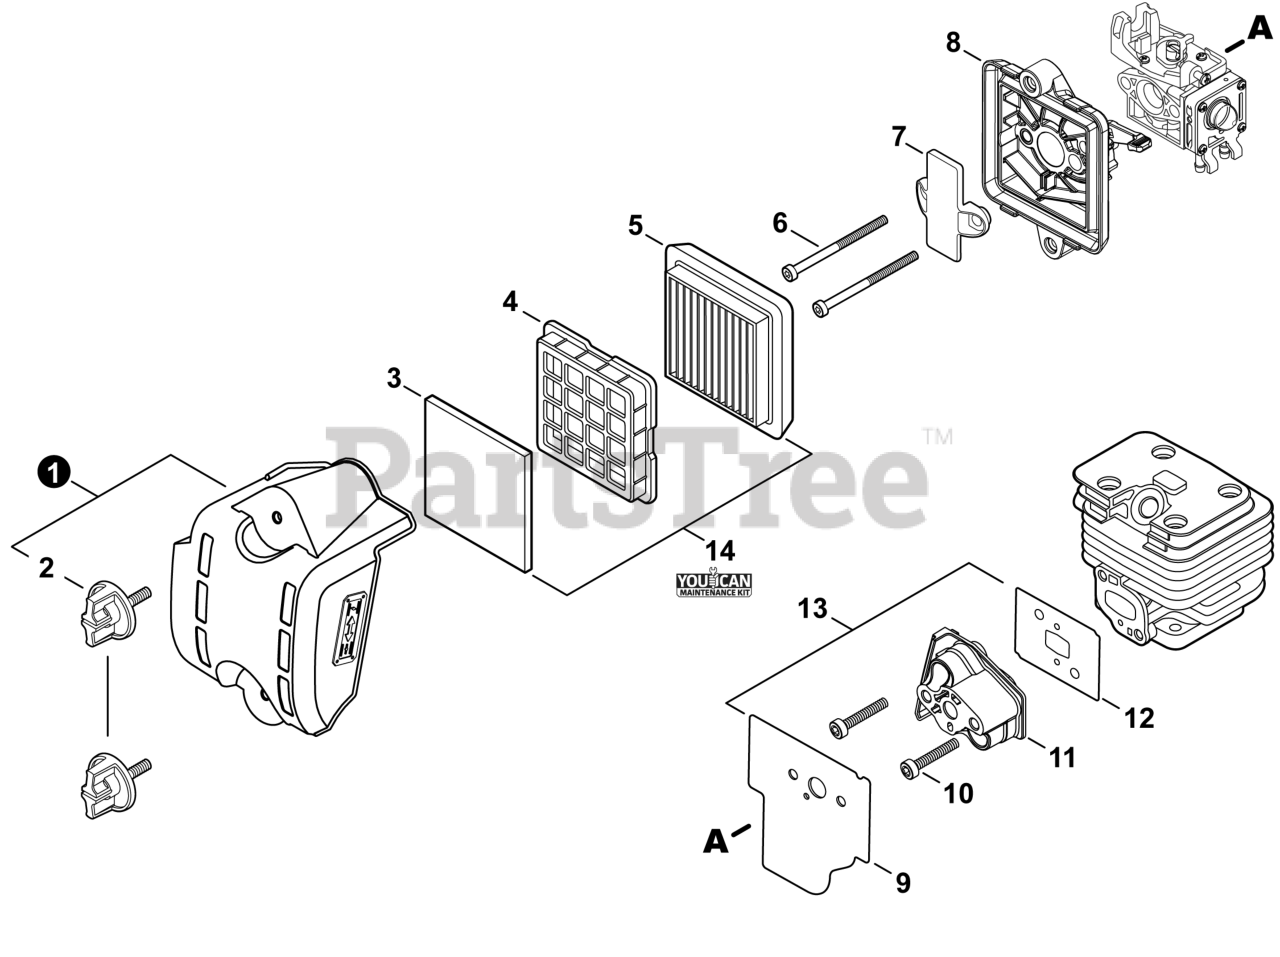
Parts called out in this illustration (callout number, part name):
1	COVER SET, AIR FILTER
2	KNOB, FASTENER
3	PRE-FILTER, FOAM
4	RETAINER, PRE-FILTER
5	FILTER, AIR
6	BOLT, TORX 5x60
7	PLATE, PREVENT
8	CASE, AIR FILTER
9	GASKET, INTAKE
10	BOLT 5x20
11	INSULATOR, INTAKE
12	GASKET, INTAKE
13	GASKET KIT: ENGINE, INTAKE, EXHAUST
14	TUNE-UP KIT - YOUCANT
